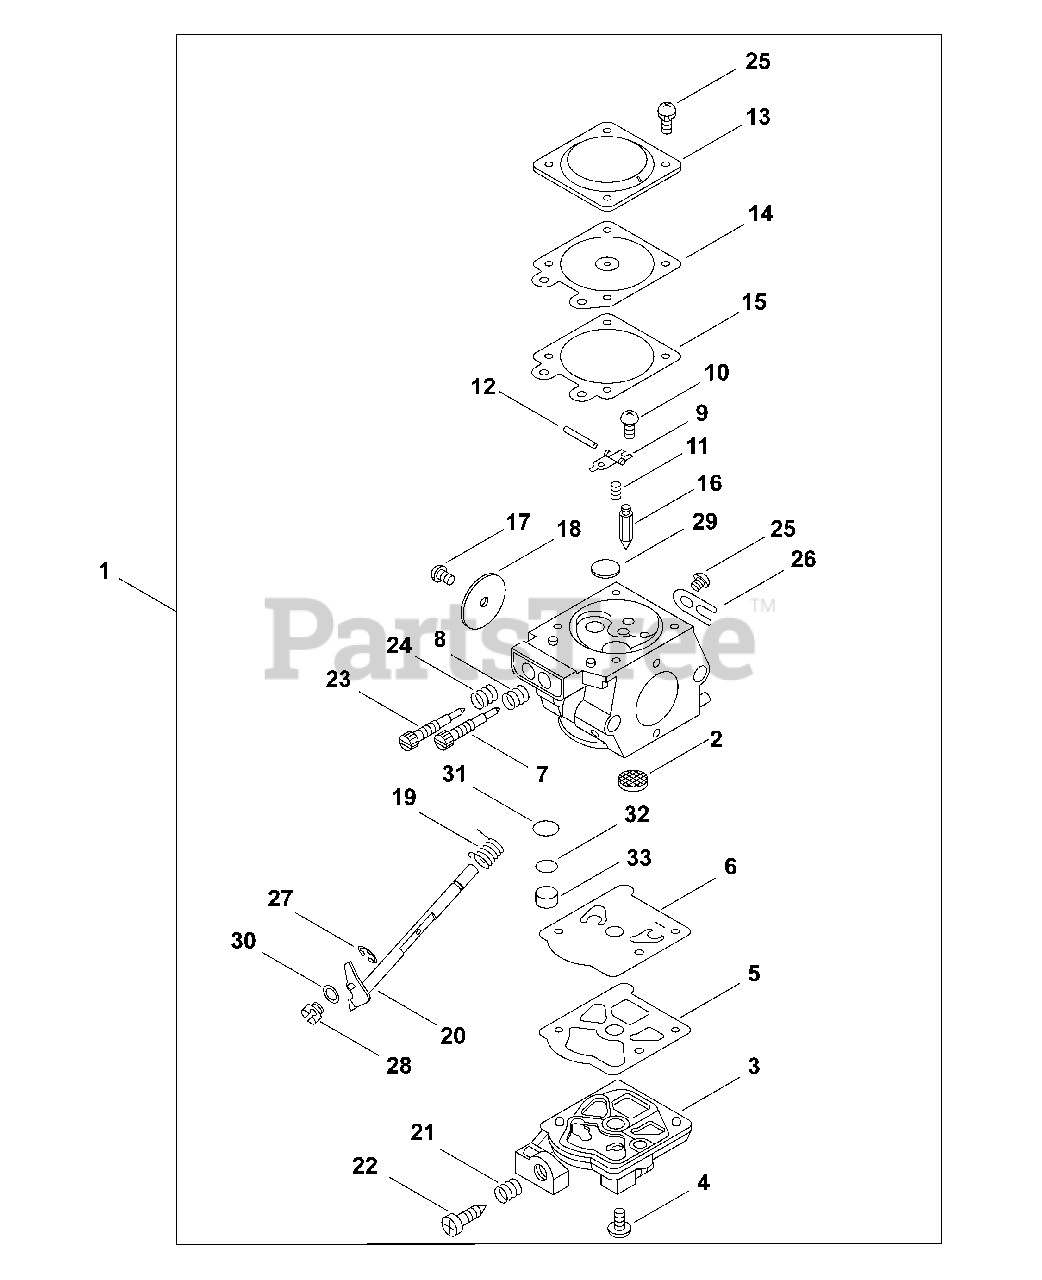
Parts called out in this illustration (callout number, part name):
1	CARBURETOR - WT-120B
2	SCREEN, FUEL INLET
3	COVER, FUEL PUMP
5	GASKET, PUMP
6	DIAPHRAGM, PUMP
7	NEEDLE, LOW SPEED
8	SPRING, NEEDLE
9	LEVER, METERING
11	SPRING, METERING LEVER
12	PIN, METERING LEVER
13	COVER, METERING DIAPHRAGM
14	DIAPHRAGM, METERING
15	GASKET, METERING DIAPHRAGM
16	VALVE, INLET NEEDLE
18	VALVE, THROTTLE
19	SPRING, THROTTLE
20	SHAFT ASSY, THROTTLE
22	SCREW, IDLE ADJUST
23	NEEDLE, HIGH SPEED
24	SPRING, HIGH NEEDLE
26	CLIP, THROTTLE SHAFT
29	PLUG, WELCH
31	SCREEN, SPARK ARRESTER
32	RING, RETAINING
33	PLUG, CUP
